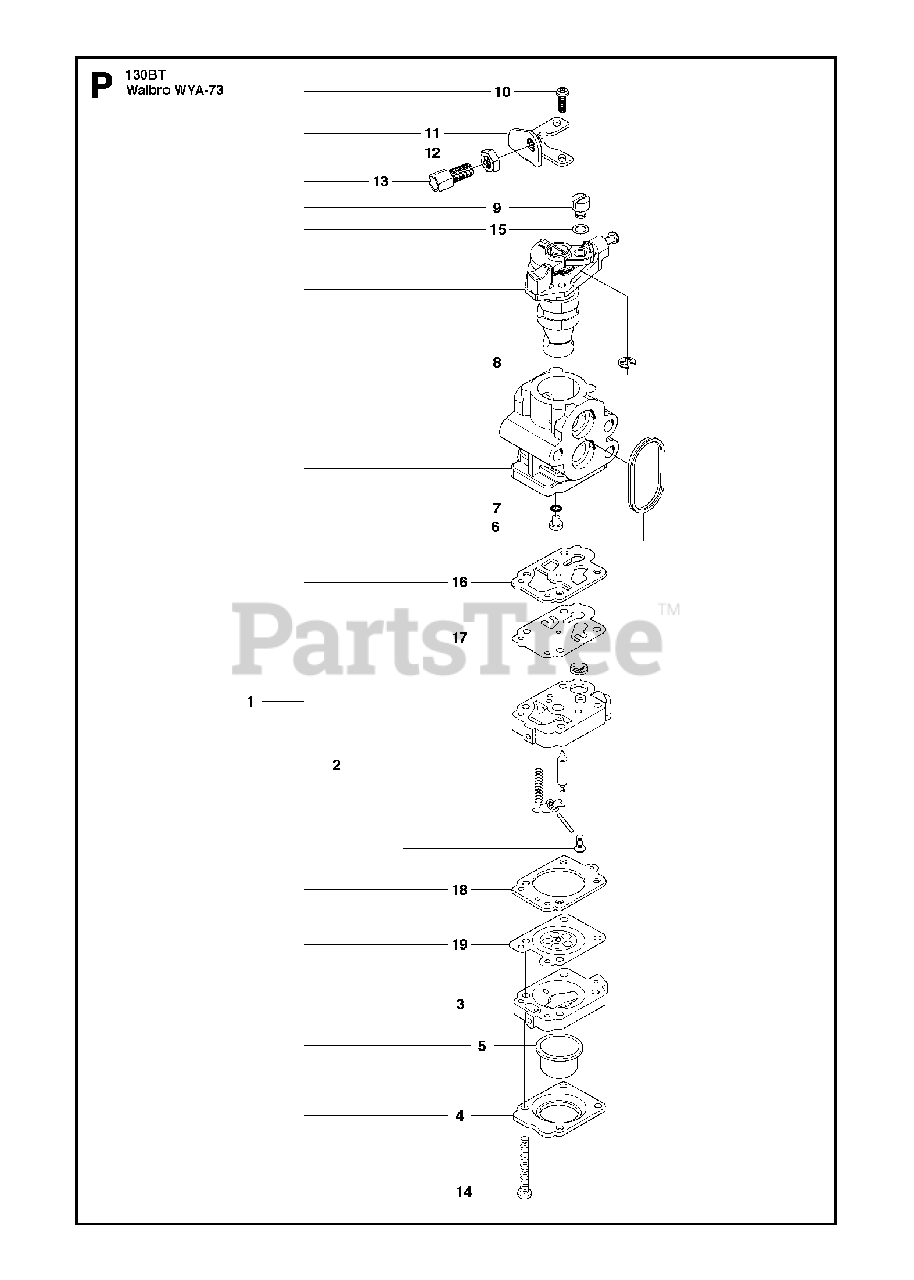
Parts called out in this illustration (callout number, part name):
1	CARBURETOR A
2	CARBURETOR BODY
3	BODY
4	1OVER
5	PUMP
6	JET
7	O-RING
8	RING
9	SWIVEL
10	SCREW
11	BRACKET
12	NUT
14	SCREW
15	WASHER
16	GASKET
17	DIAPHRAGM
18	GASKET
19	DIAPHRAGM
